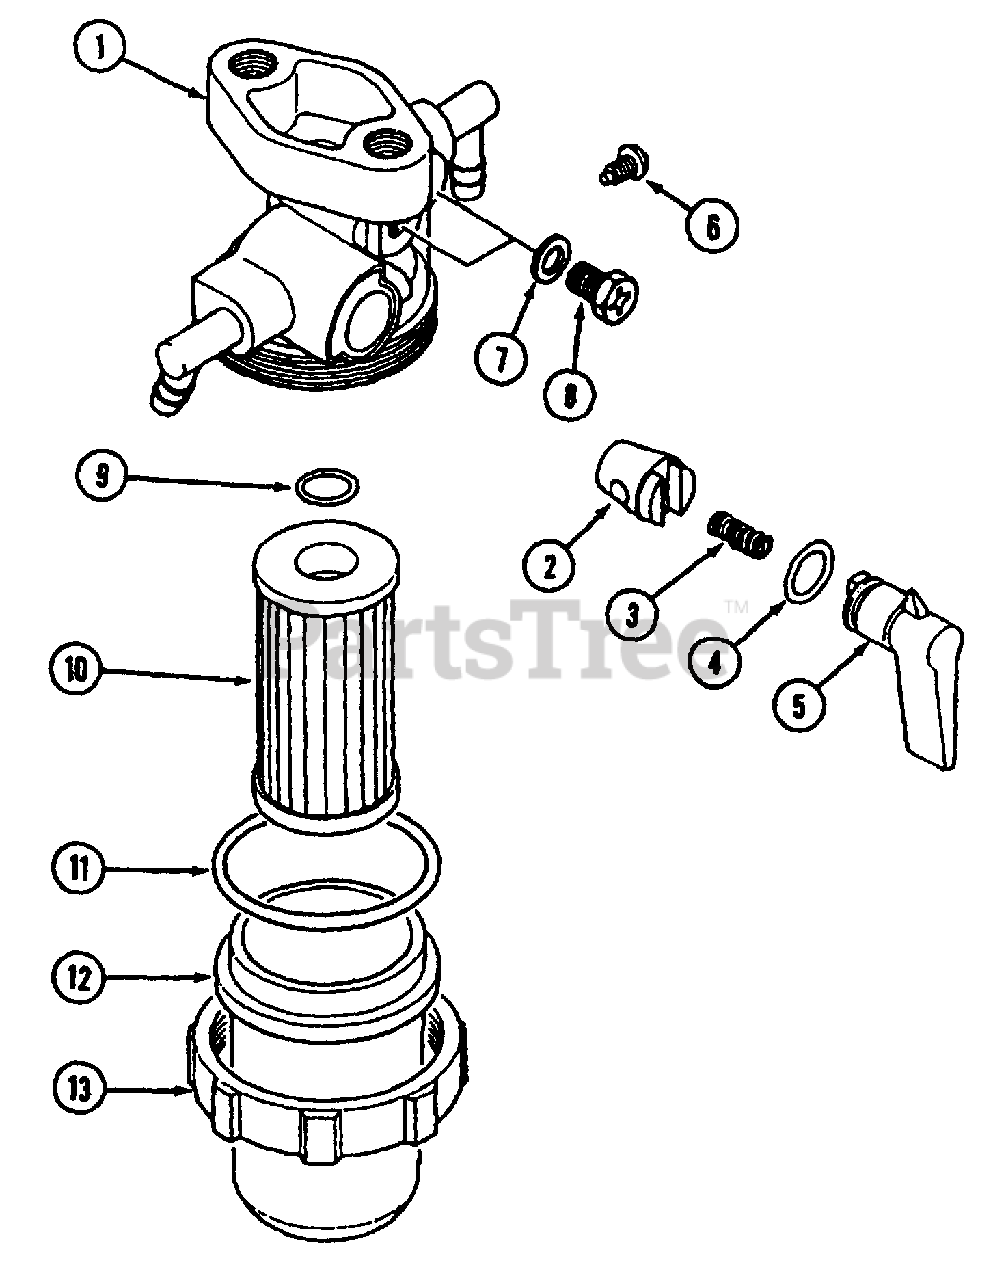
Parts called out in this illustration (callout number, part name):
1	Body Sub Ass'y., Fuel Filter
2	Valve
3	Spring, Valve
4	O-Ring, Valve
8	Screw,Air Valve
9	O-Ring, Element
10	Element
11	O-Ring, Filter Cup
12	Cup, Filter
